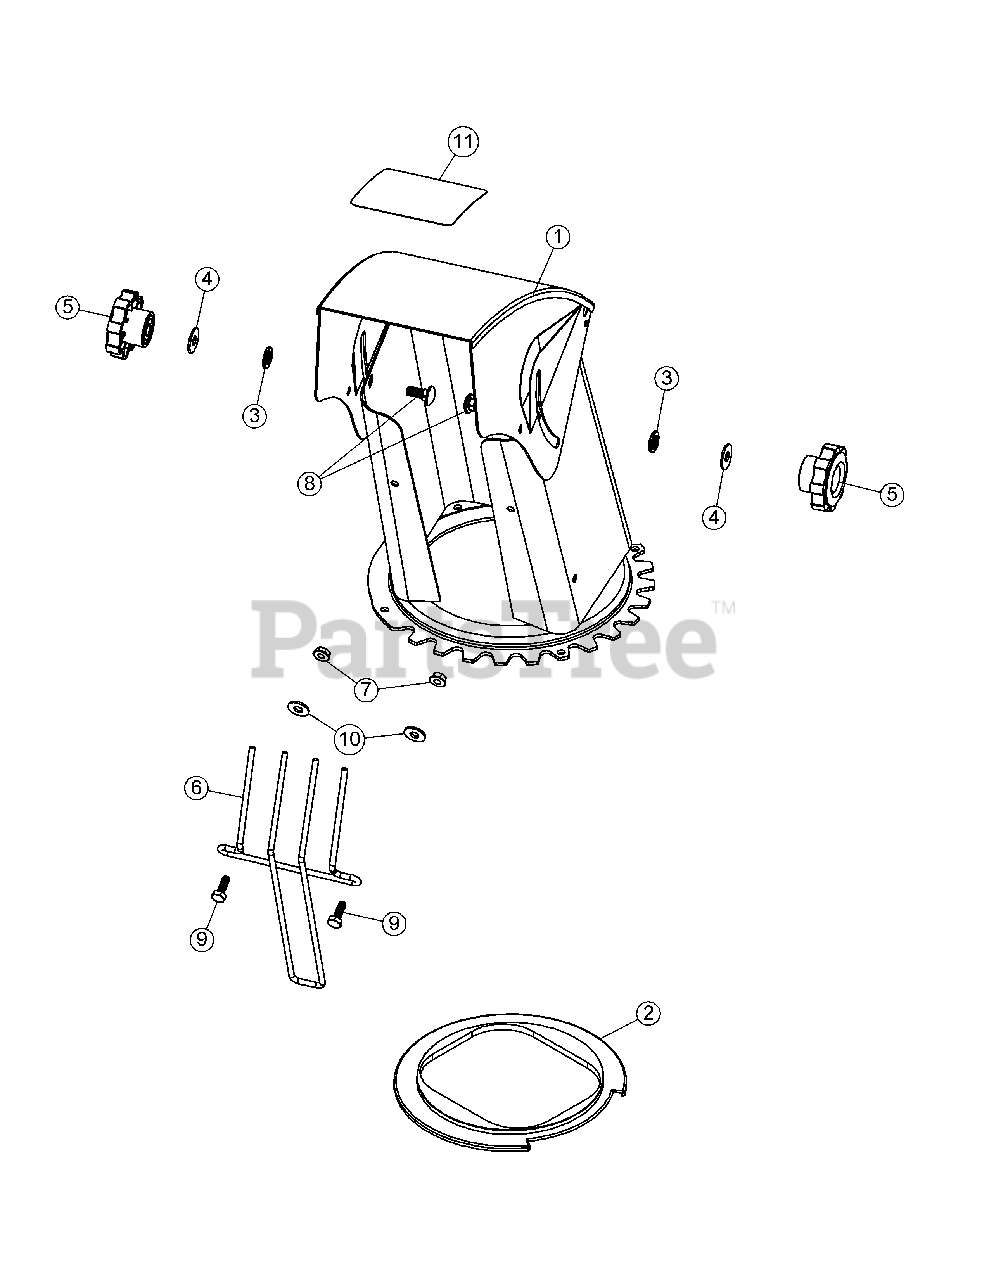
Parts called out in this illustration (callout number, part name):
1	Chute
2	Rotation ring
3	Nylon flat washer 7/16"
4	Nylon flat washer 11/32"
6	Hand guard
7	Flange nut 1/4" n.c.
8	Carriage bolt 5/16" n.c. x 3/4"
9	Hex. bolt 1/4" n.c. x 3/4"
10	Flat washer 5/16" hole
11	Danger decal chute
